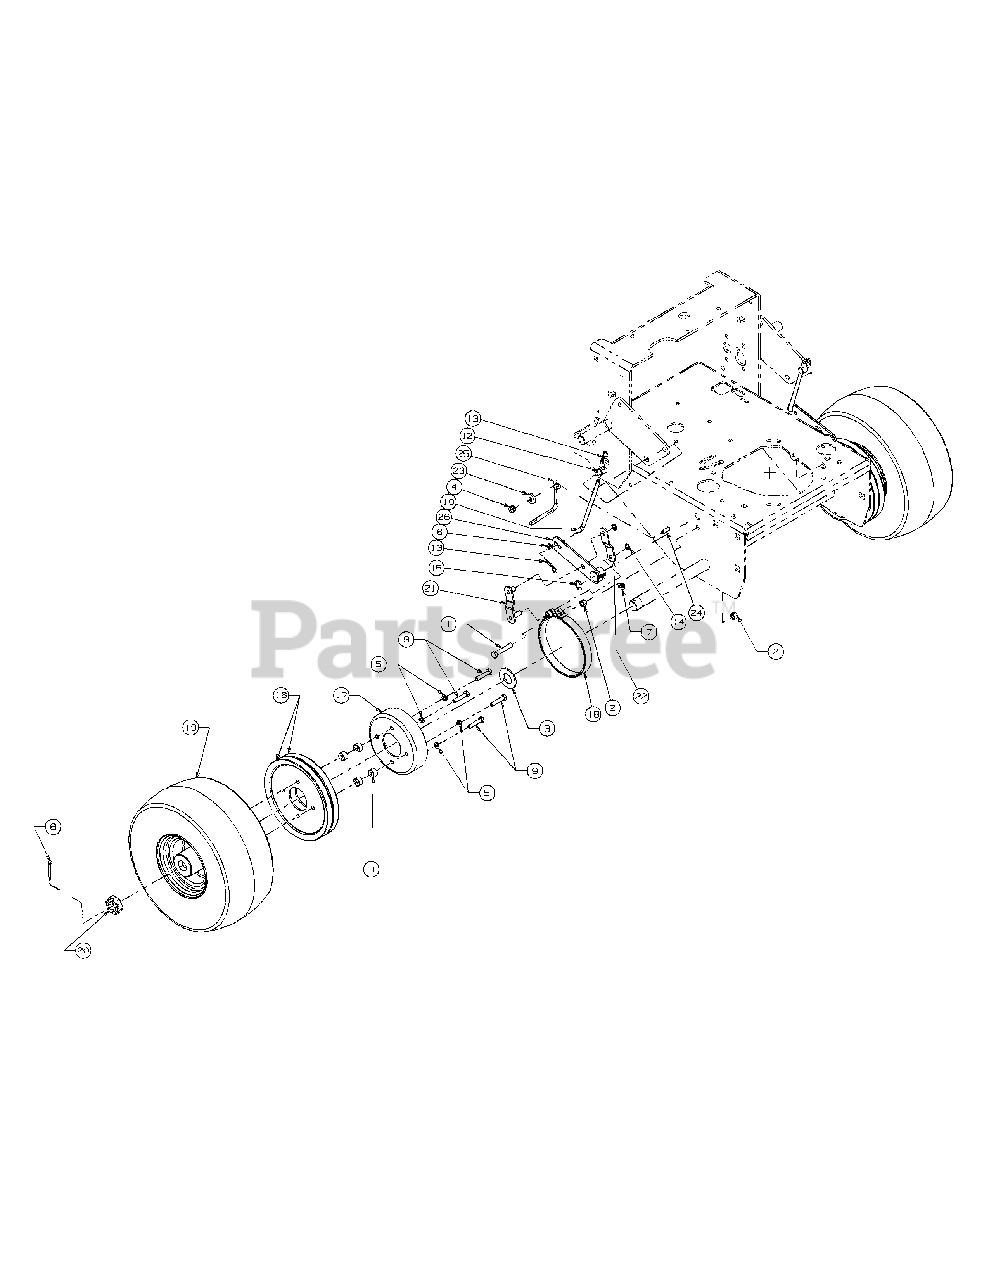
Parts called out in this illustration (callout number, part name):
1	Hex Cap Screw, 3/8-16 x 2.00
2	Hex Nut, 3/8-16
3	Flat Washer, 1.00 x 2.00 x .075
4	Nut, Nylock, 5/16-18
5	Lock Washer, 5/16 Zinc
6	Flat Washer, 5/16
7	Grease Fitting, 1/4-28, 90 degree
8	Cotter Pin, 5/32 x 1-1/2 Zinc
9	Hex Cap Screw, 5/16-18 x 1-1/2
10	Brake Rod
11	Drive Wheel Pulley Spacer
12	Swivel Joint
13	Hair Pin, 3/8-1/2
14	Retainer, Push ON, 3/8
15	E-Ring, 5/8
16	Drive Pulley, V
17	Drum Brake
18	Band Brake
19	Wheel Assembly, 13 x 6.50-6
19	Tire, 13 x 6.50-6
20	Hex Jam Nut, 1-14
21	Brake Link
22	Brake, Bracket Link
23	Idler Washer
24	Carriage Bolt, 5/16-18 x 1
25	Drive Belt Guide
26	Brake Lever Weldment
